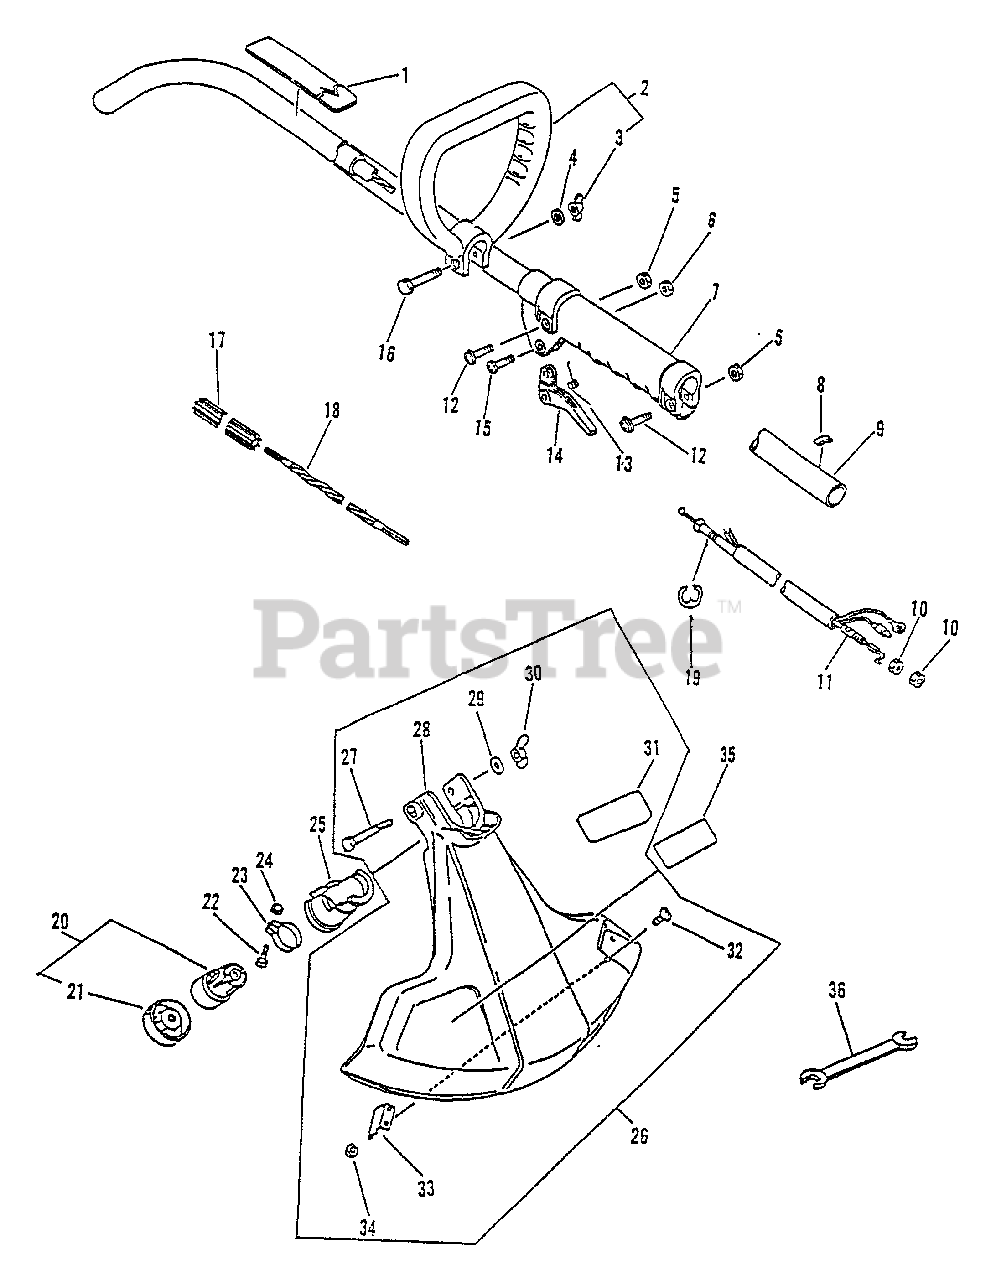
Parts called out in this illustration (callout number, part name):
1	LABEL - CAUTION
2	HANDLE ASSY
3	NUT, WING 6
4	WASHER 6.5×11.5×0.8
5	NUT M5
6	NUT, LOCK M5
8	LABEL - ALIGNMENT
9	MAIN PIPE ASSY
11	CABLE, THROTTLE
12	SCREW 5×25
13	SPRING, THROTTLE
14	TRIGGER, THROTTLE
16	BOLT - 6×40
17	LINER - FLEXIBLE
18	DRIVESHAFT - FLEXIBLE
19	RING, RETAINING - 5
20	GEAR CASE ASSY
21	PLATE, ADAPTER - UPPER
22	BOLT M5×10
24	NUT M5
25	BRACKET, BEARING CASE
26	DEBRIS SHIELD KIT
27	BOLT - 6×50
28	SHIELD
29	WASHER 6.5×11.5×0.8
30	NUT, WING 6
31	LABEL, CAUTION
32	SCREW 5×16
33	CUTTER, LINE
34	NUT M5
35	LABEL, ECHO
36	SPANNER 8×10
